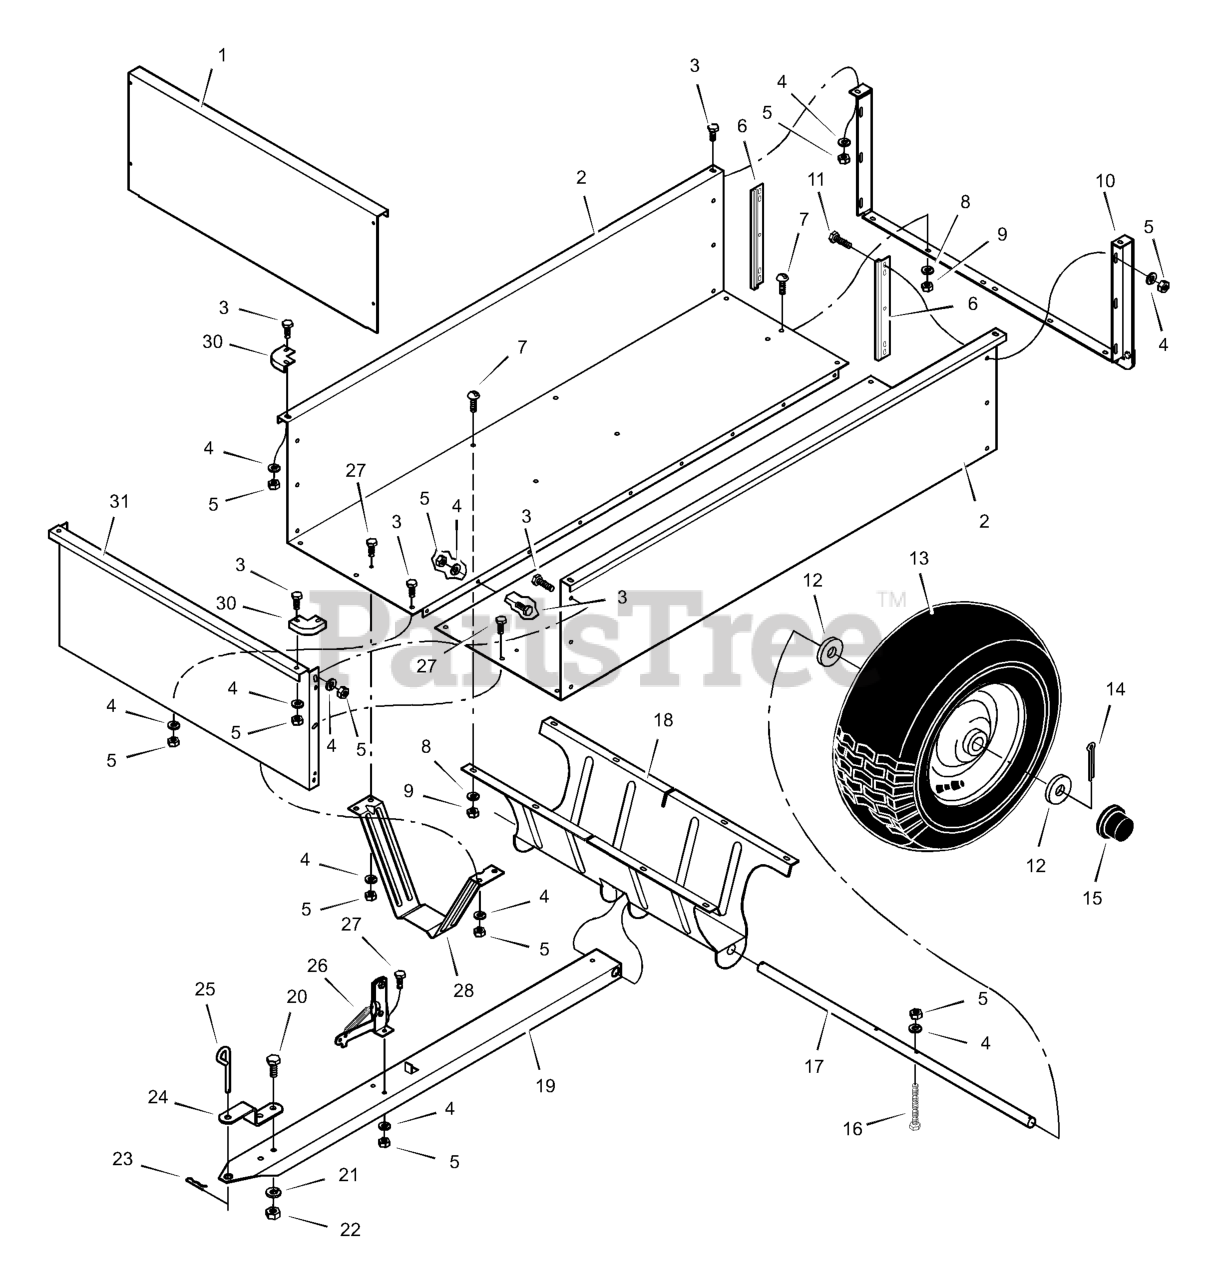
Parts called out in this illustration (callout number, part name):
1	Tailgate
2	Panels, Body
3	Bolt (M6x13)
4	Lockwasher (Size 6)
5	Nut (M6)
6	Guides, Tailgate
7	Screw (M8x20)
8	Lockwasher (Size 8)
9	Nut (M8)
10	Brace, Tailgate
11	Bolt (M6x20)
12	Washer (Size 25)
13	Wheel & Tire
14	Pin, Cotter
16	Bolt (M6x45)
18	Support, Axle
19	Drawbar
20	Bolt (M10x25)
21	Lockwasher (Size 10)
22	Nut (M10)
23	Pin, Hair
24	Bracket, Hitch Pin
25	Pin, Hitch
26	Latch, Release
27	Bolt (M6x16)
28	Support, Drawbar
30	Braces, Corner
31	Panel, Front
